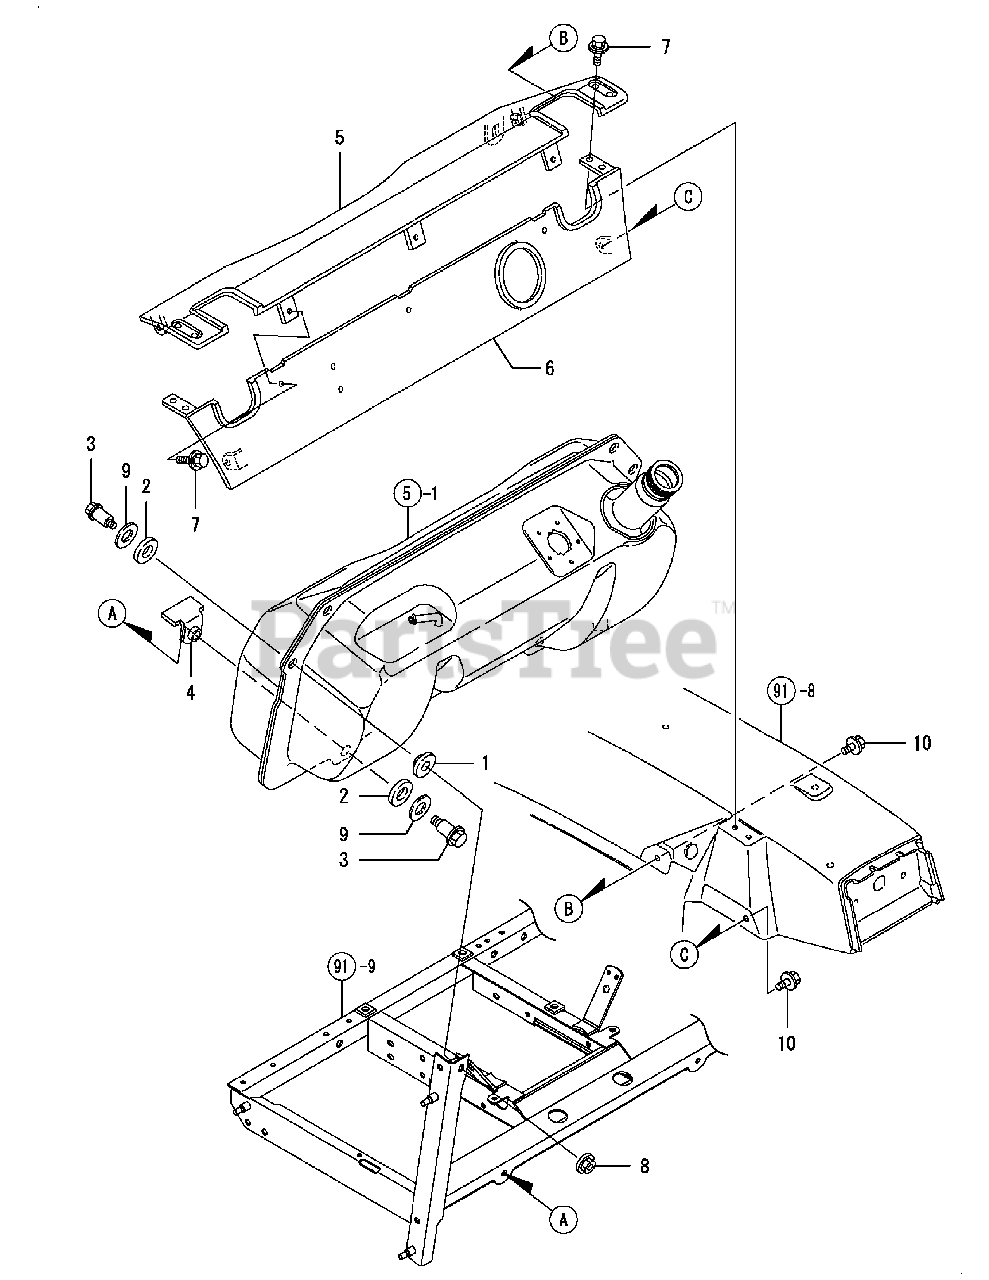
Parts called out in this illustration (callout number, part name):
1	PACKING, RUBBER
2	PACKING, RUBBER
5	COVER, TANK FRONT
6	COVER, TANK REAR
7	BOLT W/WASHER M6X16
8	NUT W/WASHER 8
10	BOLT M 8X 16 PLATED
